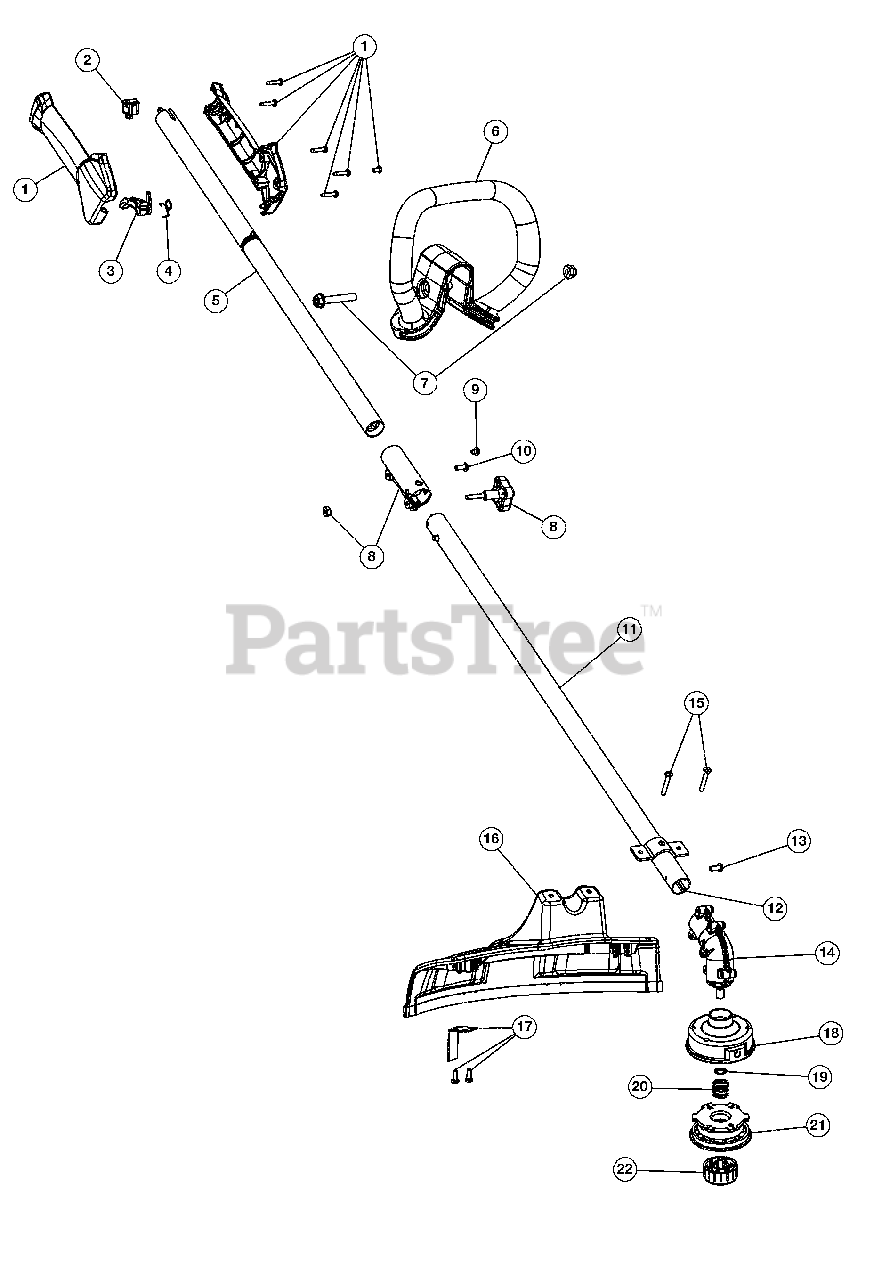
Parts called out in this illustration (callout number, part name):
1	Throttle Housing Assembly (Incl. 2-4)
2	Throttle Trigger
3	Throttle Trigger Spring
5	Upper Drive Shaft Housing Assembly
6	D-Handle (Incl. 7)
7	D-Handle Bolt
8	Split Boom Coupler (Incl. 9-10)
11	Lower Drive Shaft Housing Assembly
12	Lower Flexible Drive Shaft
13	Anti-Rotation Screw
14	Gear Box Assembly (Incl. 13 & 18-22)
15	Shield Mounting Screws
16	Shield Assembly (Incl. 15 & 17)
17	Blade Assembly
18	Outer Spool Assembly
19	Retainer
21	Inner Reel
22	Bump Knob Assembly
